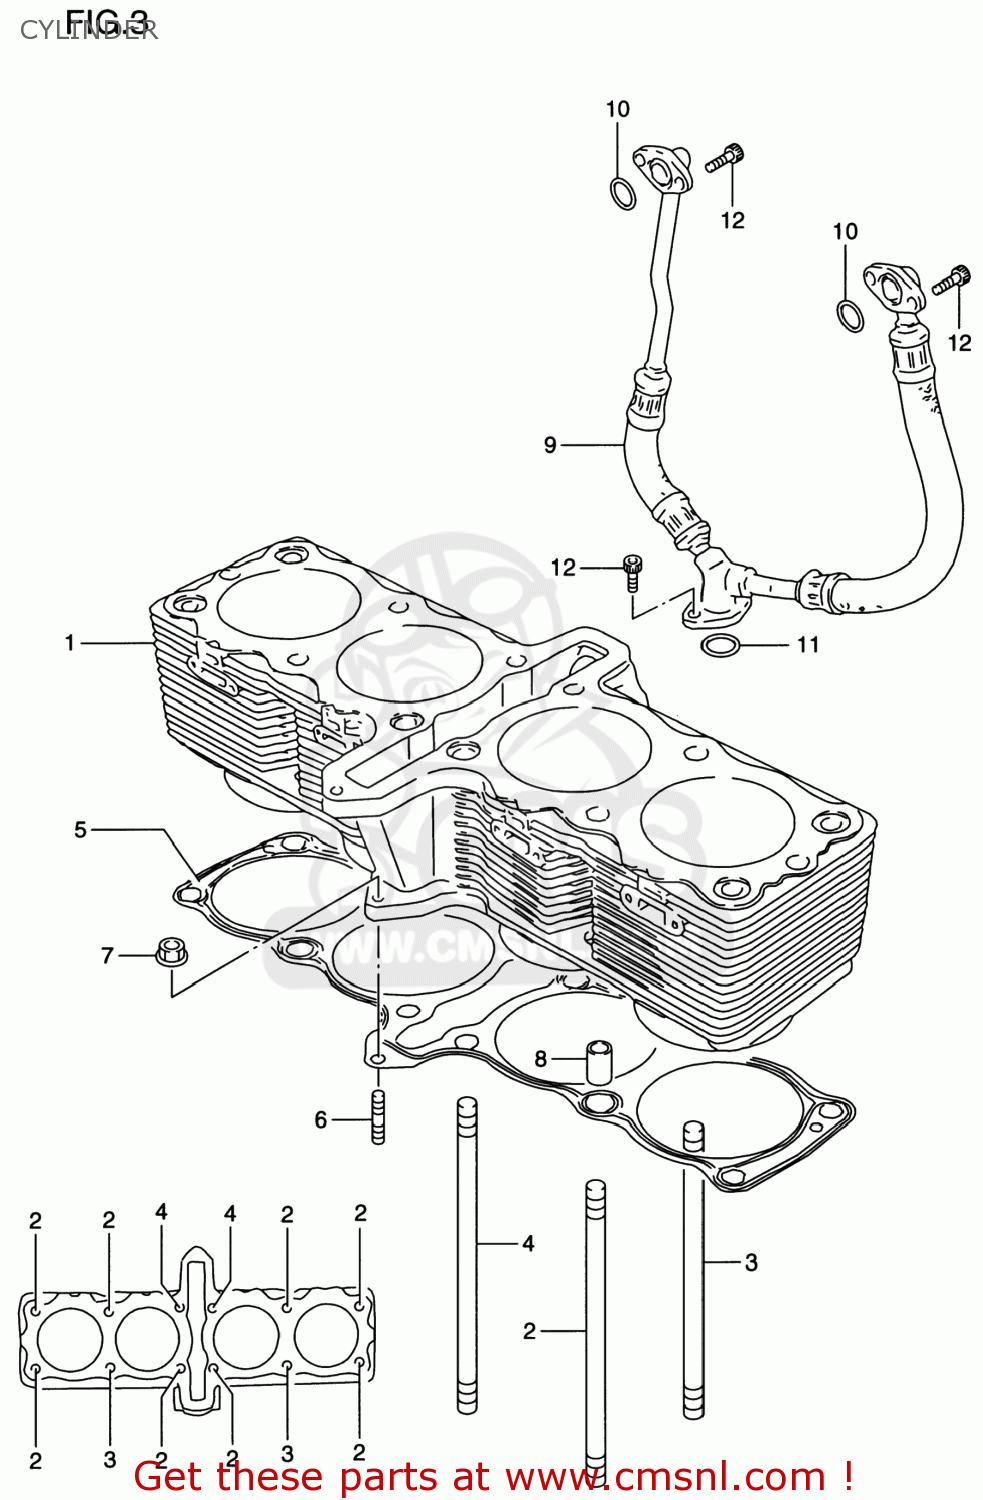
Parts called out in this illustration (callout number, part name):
1	CYLINDER
2	BOLT,STUD
3	BOLT,STUD
4	BOLT,STUD
5	GASKET,CYLINDER (NAS)
6	STUD,M6X1X32
7	NUT
8	PIN(13X10.4X20)
9	HOSE,OIL HEAD COOLER
10	O RING(D:2.5,ID:13.8)
11	O RING(D:2.4,ID:15.8)
12	BOLT,OIL FILLE
